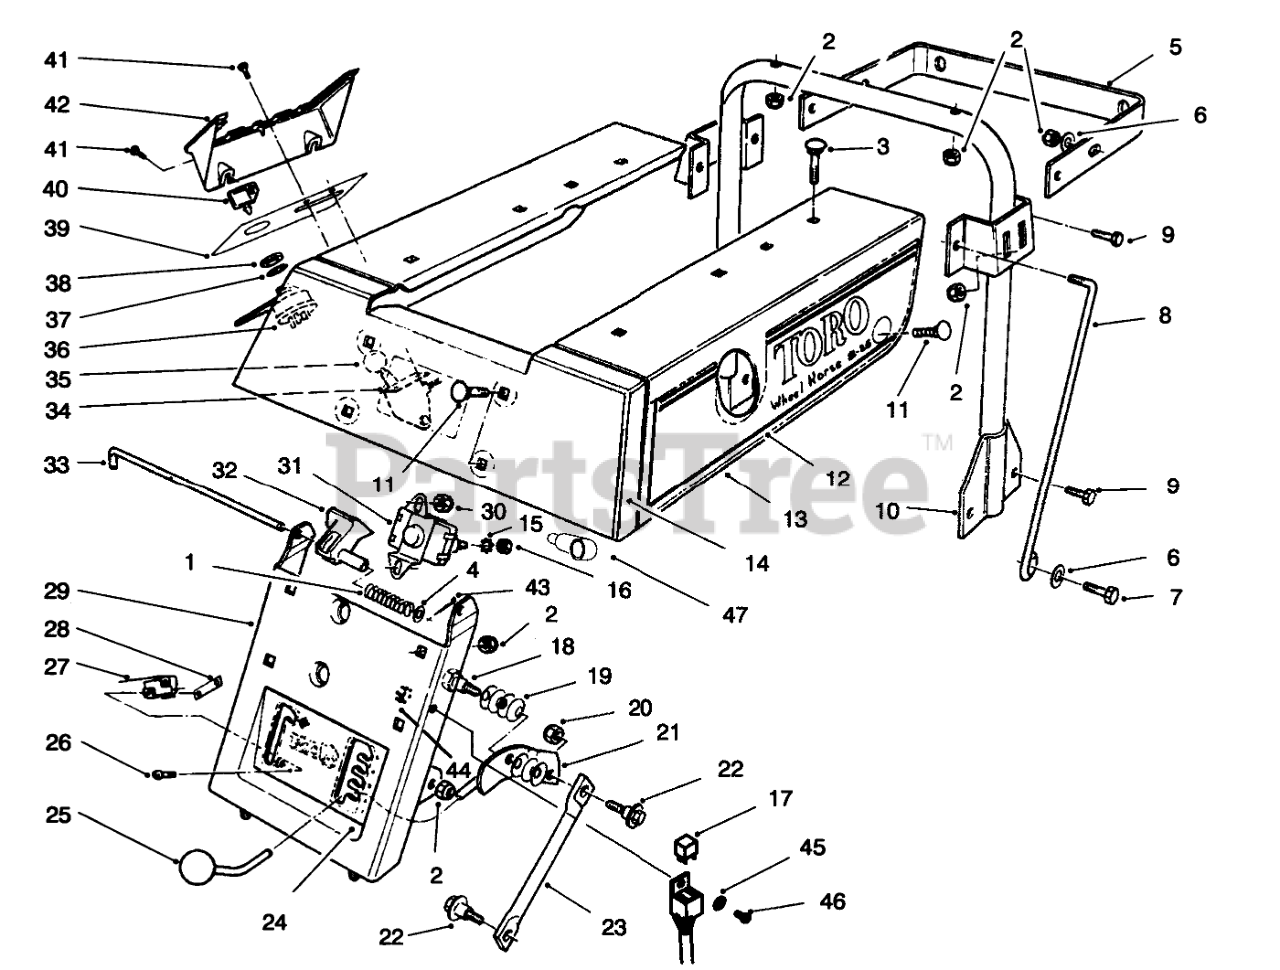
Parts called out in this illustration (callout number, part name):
1	SPRING-COMPRESSION
2	NUT-LOCK, NI
3	SCREW-CARR
4	WASHER-FLAT
5	Bar-Stand
6	WASHER-PLAIN
7	SCREW-HH
8	BRACE-SEAT SUPPORT
9	SCREW-HH
10	SEAT SUPT WA (BLACK)
11	SCREW-CARR
12	DECAL - LH SIDE PLATE
13	SEAT BODY WA (RED)
14	DECAL - W.H. INSIGNA
15	WASHER-LOCK
16	NUT-JAM
17	RELAY
18	BOLT-SHOULDER
19	WASHER-BELLEVILLE
20	NUT-LOCK, NI
21	HOC HDLE WA
22	BOLT-SHOULDER
23	LINK-HOC
24	DECAL - HOC/DECK ENGAGE
25	KNOB-CONTROL
26	SCREW-SPH
27	SWITCH-MICRO
28	NUT-SPEED
29	FRT SEAT SUP WA RED
30	NUT-LOCK, NI
31	Solenoid
32	PROP-SEAT
33	ROD-SEAT BASE
34	CONTROL-THROTTLE
35	Knob
36	Switch-Ignition (Incl. Ref. #37 & 38)
37	WASHER-TOOTH, INTERNAL
38	NUT-HH
39	DECAL - CONTROL PANEL
40	KEY-IGNITION
41	SCREW-THD FORM, HWH
42	COVER-CONTROL PLATE
43	PIN-COTTER
44	NUT-LOCK, NI
45	WASHER-FLAT
47	BOOT-INSULATOR, TERMINAL
